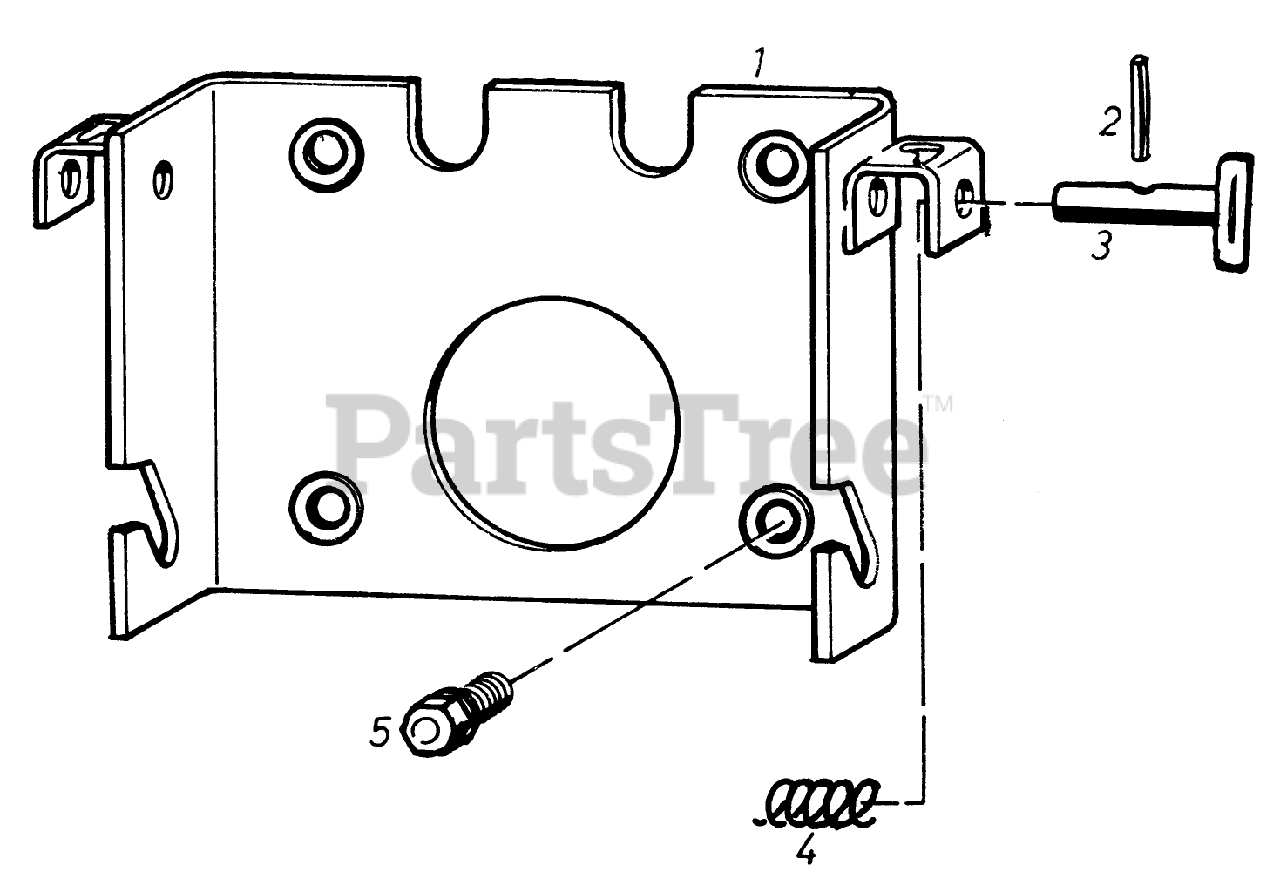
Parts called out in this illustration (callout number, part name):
1	Mounting Plate
2	Rollpin
3	Locking Pin
4	Spring
